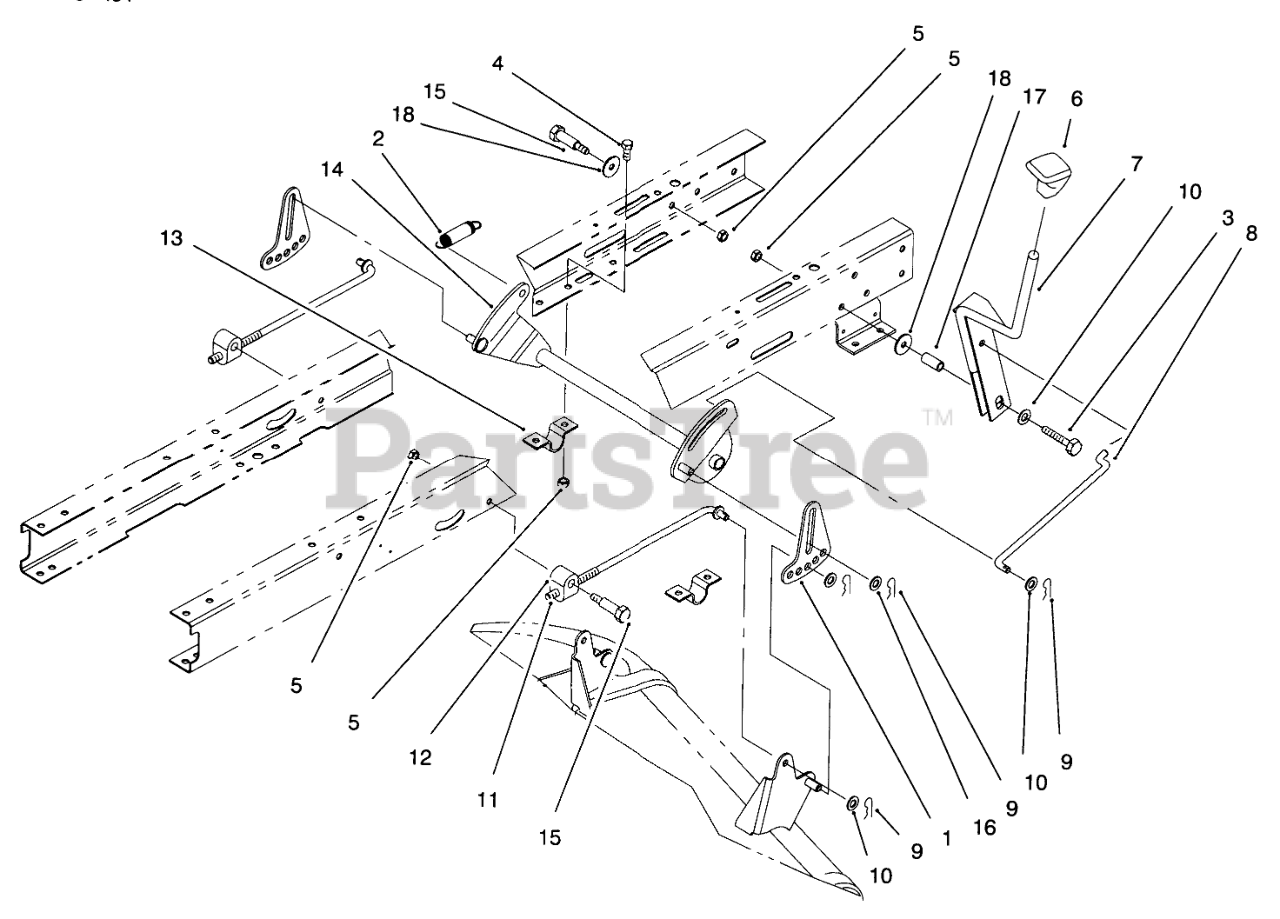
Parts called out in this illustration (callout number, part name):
1	Link-Adjusting H.O.C
2	SPRING-EXTENSION
3	SCREW-HH
4	SCREW-HH
5	NUT-LOCK, NI
6	KNOB-SHIFT
7	Lever-H.O.C.
8	LINK-HOC
9	PIN-COTTER
10	WASHER-FLAT
11	ROD-HANGER, REAR
12	TRUNNION-HOC
13	CLAMP-PIVOT, HOC
14	Pivot-H.O.C.
15	SCREW-SHOULDER, HH
16	WASHER-HARDENED
17	SPACER
18	WASHER-PIVOT
